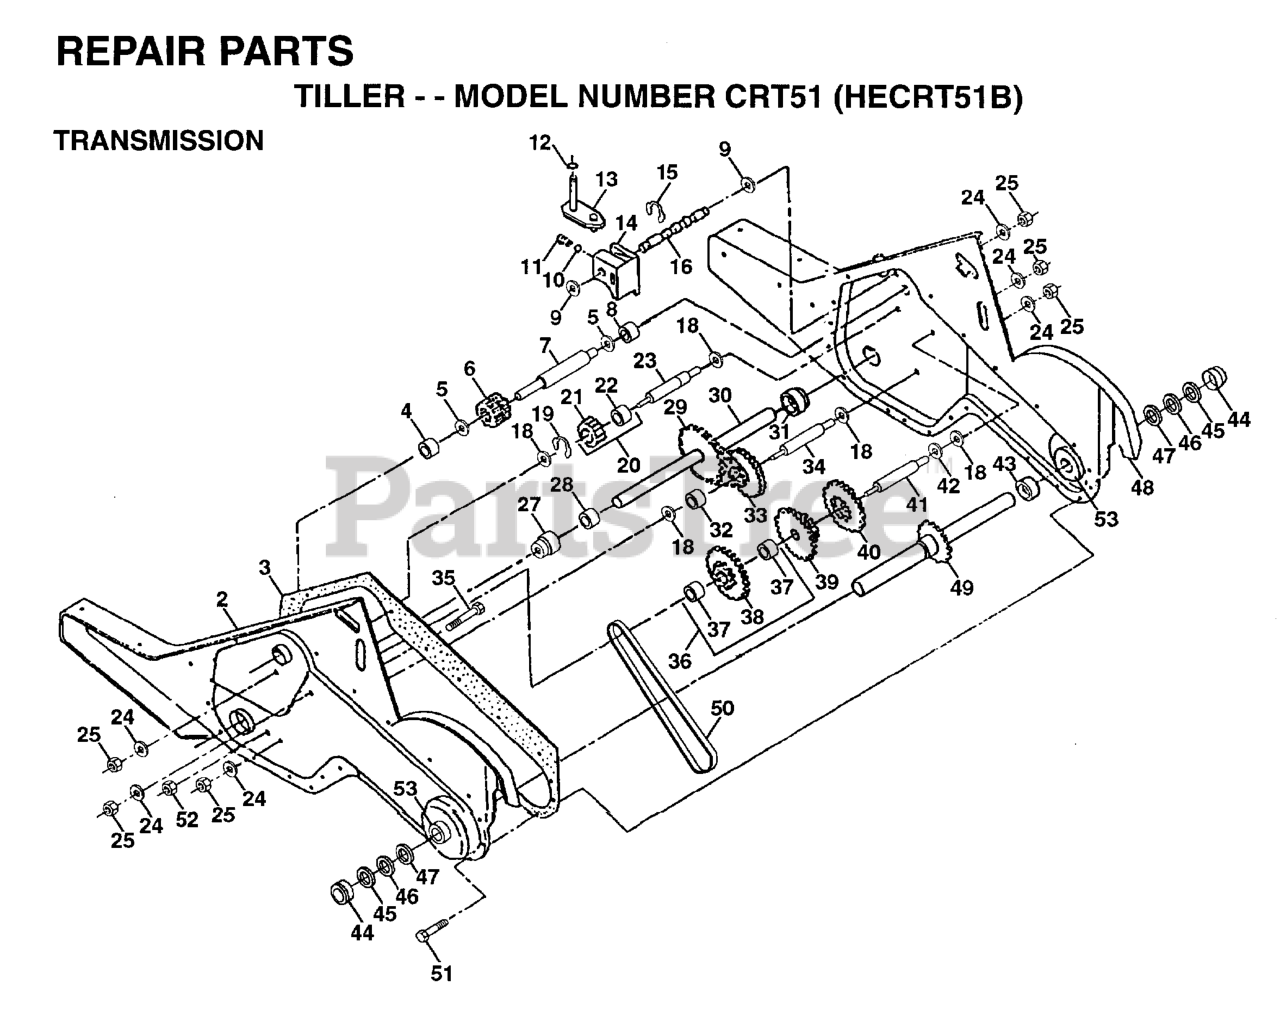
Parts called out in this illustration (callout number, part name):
1	TRANSMISSION ASSY
2	GEARCASE LH W/BRG
3	GASKET TI
4	NEEDLE BRNG LT
5	THRUST WASHER
6	GEAR.PINION.INPUT
7	SHAFT.INPUT."D".TILLER
8	BEARING TI
9	WASHER, SEAL (2 2)
10	STEEL BALL KIT
11	SPRING-SHIFT CRT
13	BRACKET ASM.SHIFT.CRT
14	SHIFT FORK TI
16	SHAFT.SHIFTER.TILLER
20	GEAR ASSY CRT
21	GEAR-REV IDLR CRT
22	NEEDLE BEARING TI
24	LOCKWASHER
25	NUT.ASF.HEX.7/16
27	BEARING, SHAFT LH CRT
30	GROUND SHAFT ASS'Y
31	BEARING, SHAFT RH CRT
33	SPRCKT 8 GEAR CRT
34	SHAFT.SECONDARY.REDUCTION.CRT
35	SCRW WHIZ LOK CRT
36	SPROCKET.ASM.W/BEARING.TILLER
37	BEARING
38	SPROCKET, TINE
41	SHAFT.REDUCTION.TILLER
42	BRNG RACE T
44	CUP
45	RING.SPIRAL.CRT.TILLER
47	OIL SEAL STD
48	GEARCASE RH W/BRG
49	TINE SHAFT
50	CHAIN.TILLER
51	SCREW
53	BEARING KIT
